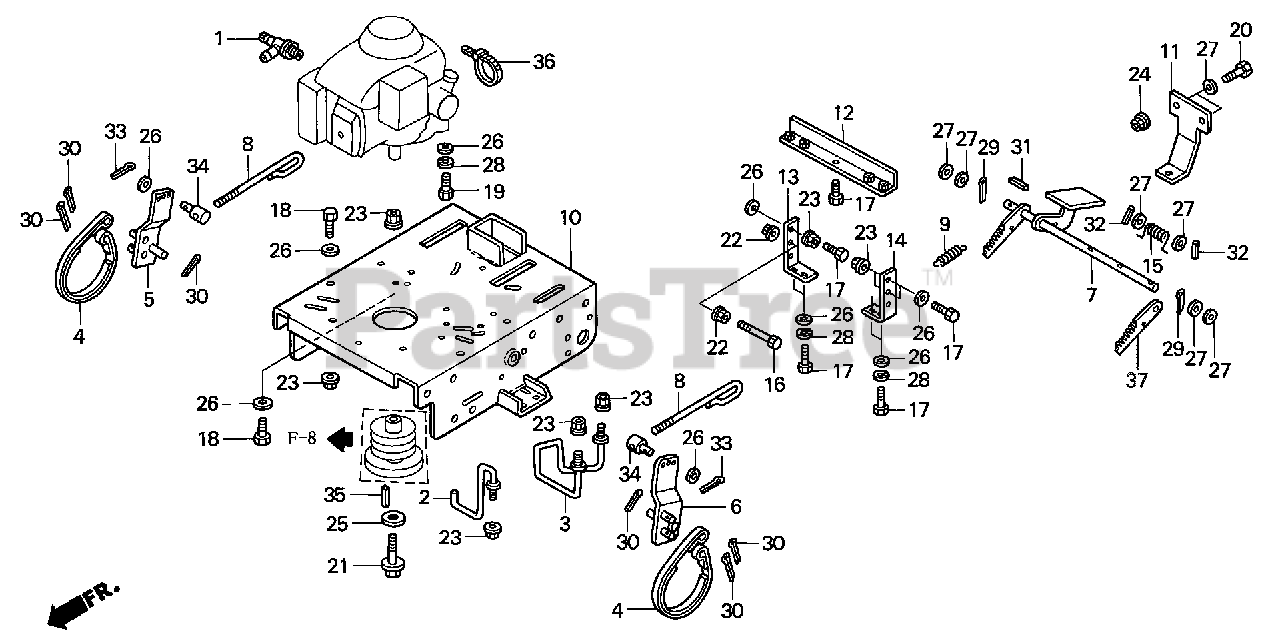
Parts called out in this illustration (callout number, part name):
1	VALVE, OIL SHUT-OFF
2	STOPPER B, BELT
3	ROD A, BELT STOPPER
4	BAND, BRAKE
5	ARM, R. BRAKE
6	ARM, L. BRAKE
7	LEVER, PARKING BRAKE
8	ROD, BRAKE
9	SPRING, PARKING BRAKE RETURN
10	BED, ENGINE
11	SUPPORT, ENGINE BED
12	PLATE, TRANSMISSION MOUNTING
13	BRACKET, R. TRANSMISSION MOUNTING
14	BRACKET, L. TRANSMISSION MOUNTING
15	SPRING, L. GUARD RETURN
16	BOLT, HEX. (1/4-20X2") (NOT AVAILABLE)
17	BOLT, HEX. (5/16-18X1")
18	BOLT, HEX. (5/16-18X1 1/2")
19	BOLT, HEX. (5/16-24X1")
20	BOLT, HEX. (3/8-16X1 1/4")
21	BOLT, FLANGE (7/16-20X2")
22	NUT, WHIZ-LOCK (1/4"-20)
23	NUT, WHIZ-LOCK (5/16"-18)
24	NUT, WHIZ-LOCK (3/8"-16)
25	WASHER (7/16")
26	WASHER, FLAT (5/16")
27	WASHER, FLAT (3/8")
28	WASHER, LOCK (5/16")
29	PIN, COTTER (7/64"X3/4")
30	PIN, COTTER (1/8"X1 1/4") (NOT AVAILABLE)
31	PIN, ROLL (3/16X1 1/2")
32	PIN, ROLL (3/16X2")
33	PIN, COTTER (3/32" X 3/4")
34	PIN, PIVOT (5/16)
35	KEY (1/4X1/4X3")
36	TIE, FUEL TUBE
37	ARM, PARKING BRAKE
